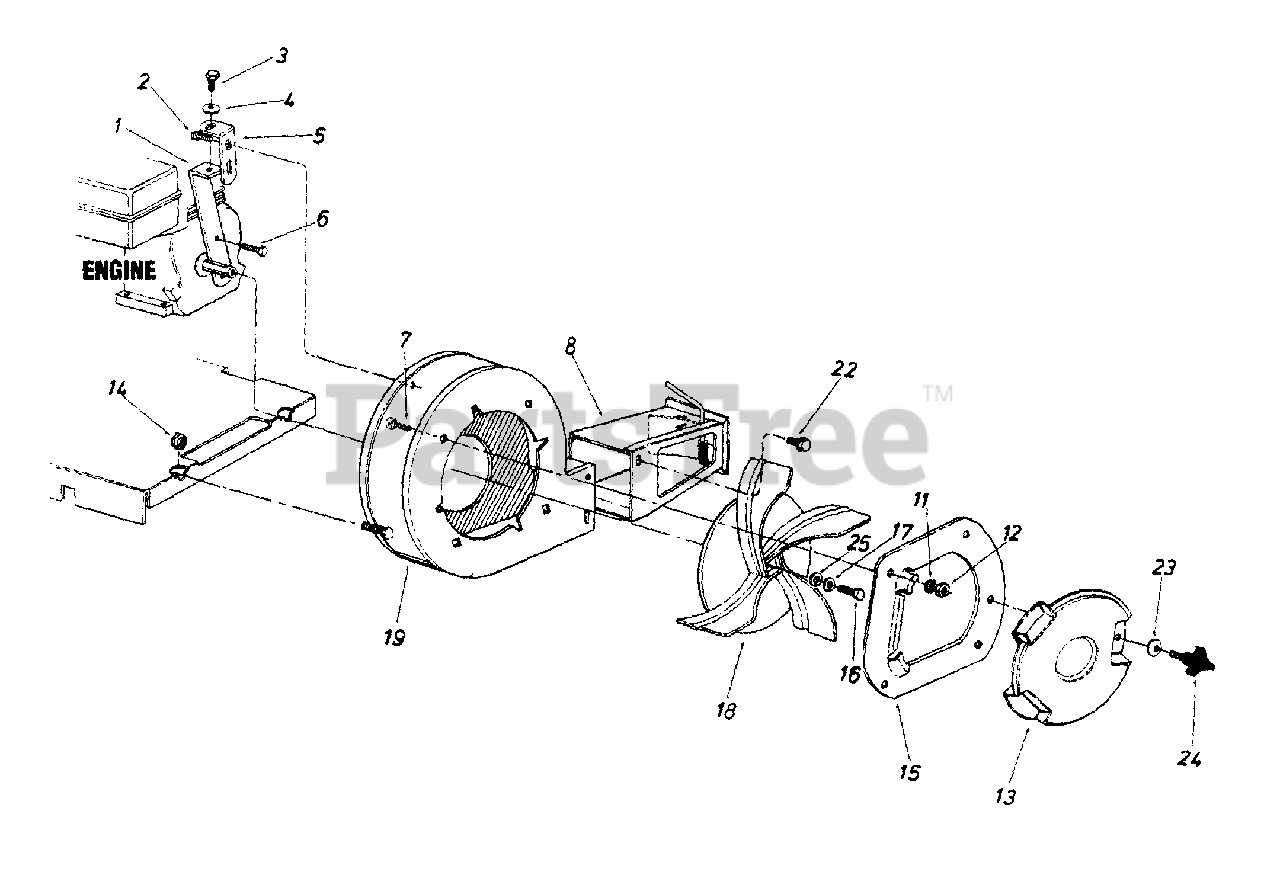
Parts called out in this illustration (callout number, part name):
3	Hex Bolt 5/16-18 x .75" Lg.
4	L-Wash. 5/16" I.D.
7	Carriage Bolt 5/16-18 x .62"
12	Hex Nut 5/16-18 Thd. (Gr. 5)
13	Blower Guard
14	Hex Shoulder Nut .50" I.D.
17	L-Wash. 3/8" I.D. - H.D.
18	Air Vane Plate Ass'y.
23	Belt-Wash. .34" I.D. x .87" O.D.
24	3-Arm Thumb Scr. 5/16-18 x .75" Lg.
25	Flat Washer
